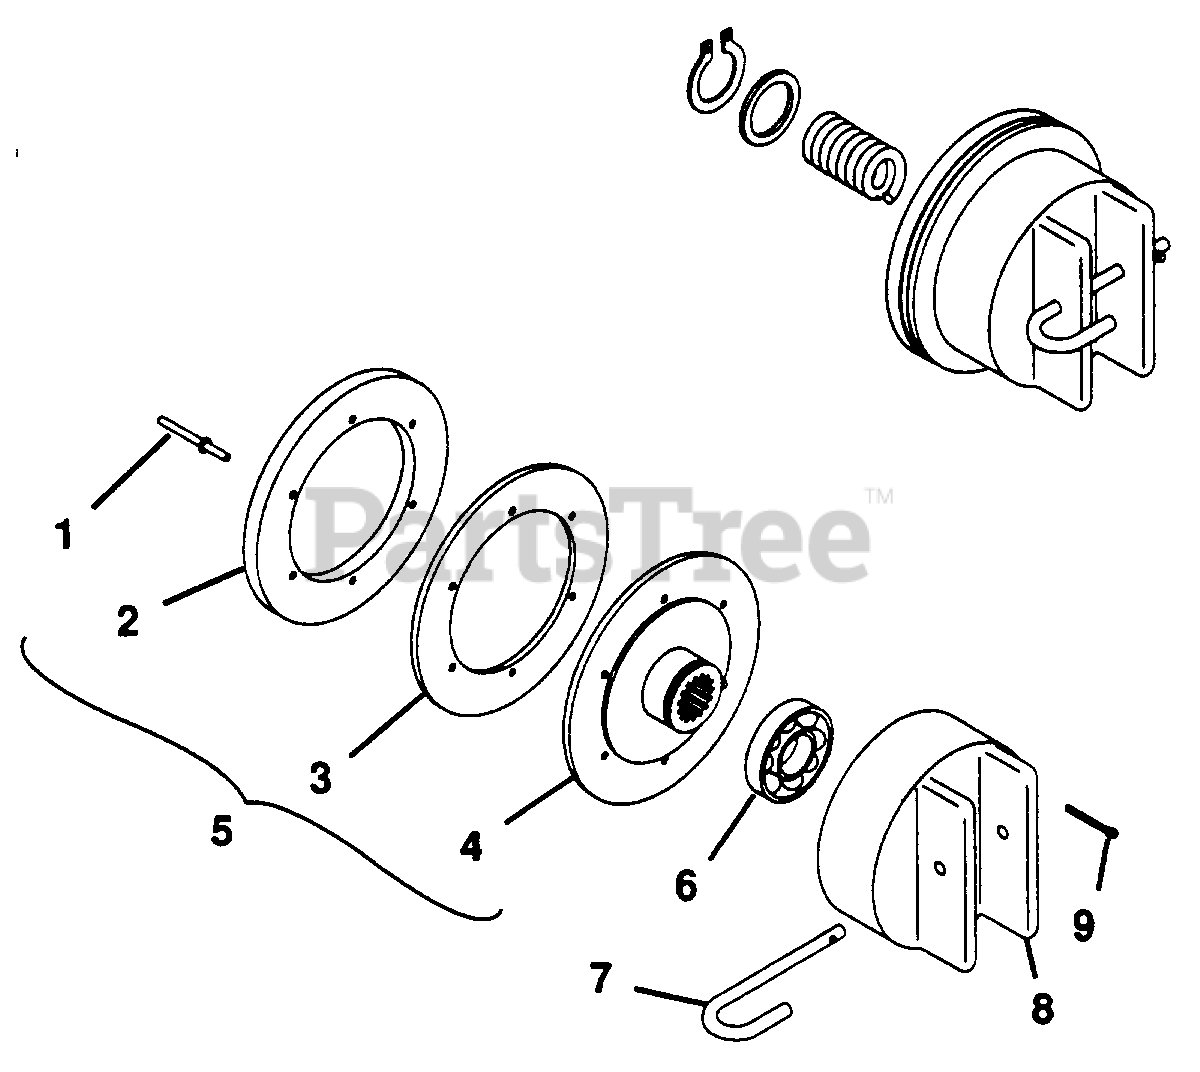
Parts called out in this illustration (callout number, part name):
1	RIVET, STEEL(BAG OF 50)
2	LINING, CLUTCH
3	RING, CLUTCH
4	DISC, CLUTCH
5	ASSEMBLY, CLUTCH AND RING
6	BEARING, BALL 1.574X3.149X.708
7	PIN, CLUTCH SPRING
8	TRUNNION, FWD-REV CLUTCH
9	PIN, COTTER .06X.75
